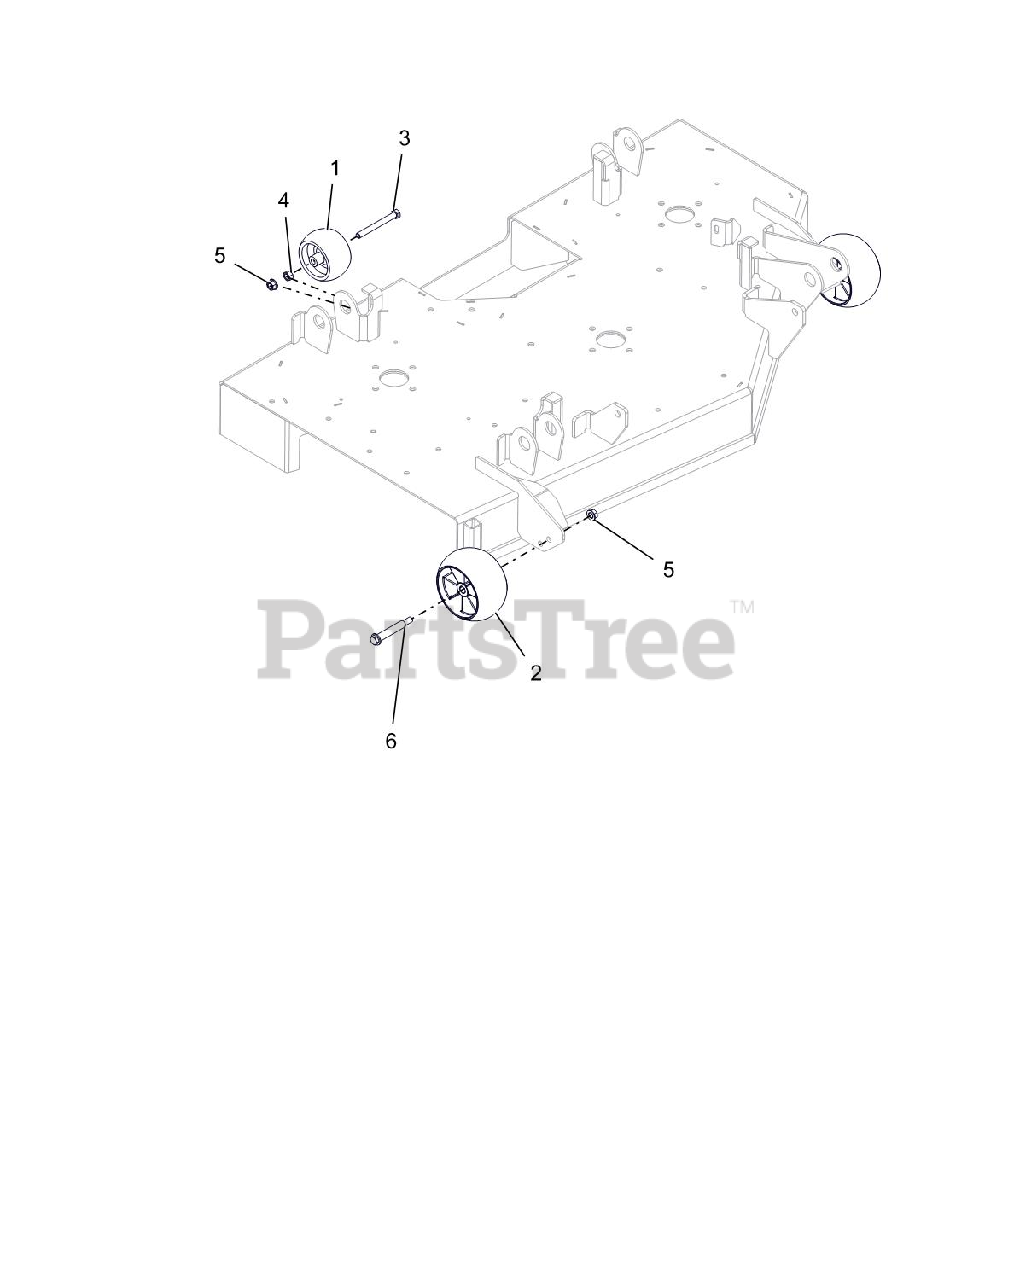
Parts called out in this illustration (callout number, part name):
2	ANTI-SCALP WHEEL - 5X OS
3	BLT-HEX .38-16X3.50 GR5 YWZC
4	NUT-HEX .38-16 YWZC
5	NUT-LK-TOP-FLG .38-16 YWZC
6	BLT-SHLDR .38-16X2.50 HWH G5YZ
